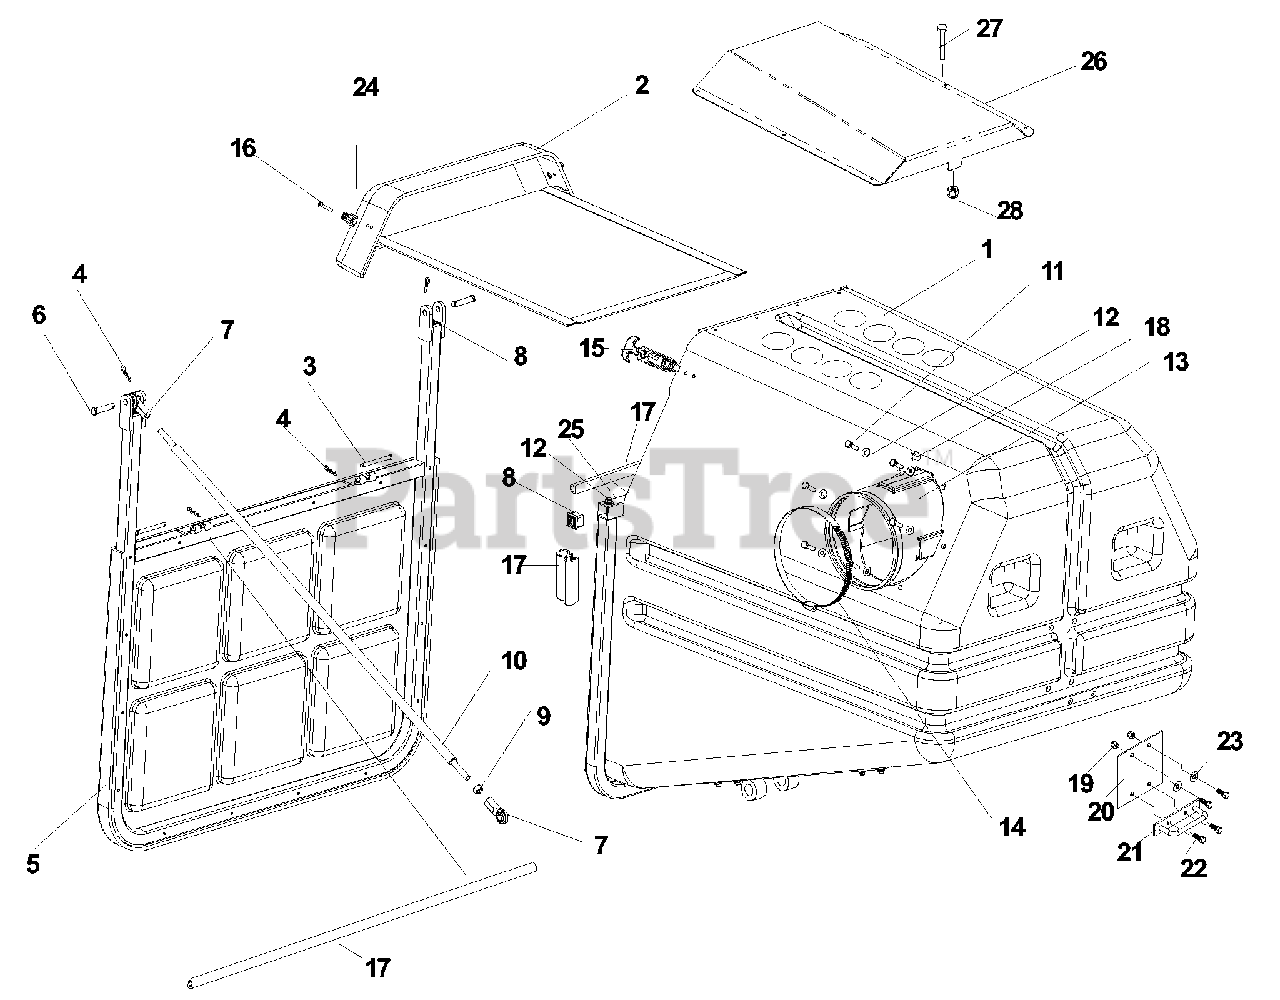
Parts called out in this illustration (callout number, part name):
1	CONTAINER ASM.
2	EXHAUST ASM.
3	CLEVIS PIN, 1/4 X 2 3/4
4	HAIR PIN, #13
6	CLEVIS PIN, 3/8 X 1 3/4
7	ROD END
9	NUT, 3/8-24
10	ARM
11	BOLT, 1/4-28 X 1
12	WASHER, 1/4
14	HOSE CLAMP
15	RUBBER LATCH
16	SCREW, 10-24 X 1 1/4, P.T.H.
17	DOOR SEAL KIT
18	NUT, 1/4-20, NYLOC
19	NUT, 3/8-16, NYLOC
20	BACK PLATE
21	LATCH
22	BOLT, 3/8-16 X 1
23	WASHER, 3/8
24	LATCH BASE
25	BOLT, 1/4-20 X 2
27	SCREW #10-24 X 3/4 STD RD
28	NUT #10-24, NYLOC
